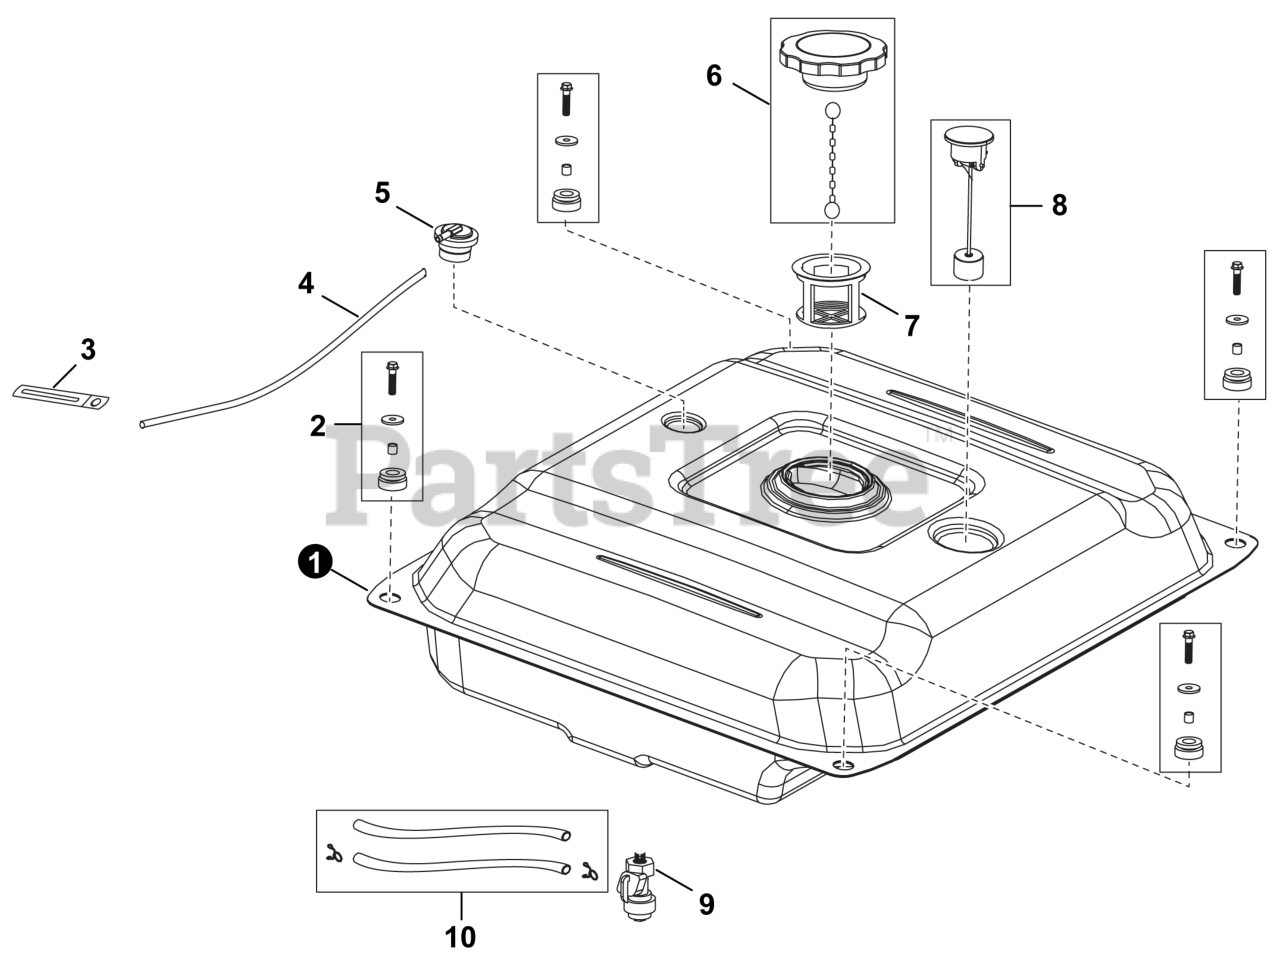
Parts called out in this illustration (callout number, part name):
1	TANK, FUEL
2	MOUNTING KIT, FUEL TANK
4	HOSE, FUEL VENT
5	VALVE, ROLL OVER
6	CAP, FUEL TANK
7	STRAINER, FUEL
8	GAUGE, FUEL
9	VALVE, FUEL SHUT OFF
10	HOSE ASSY., FUEL
